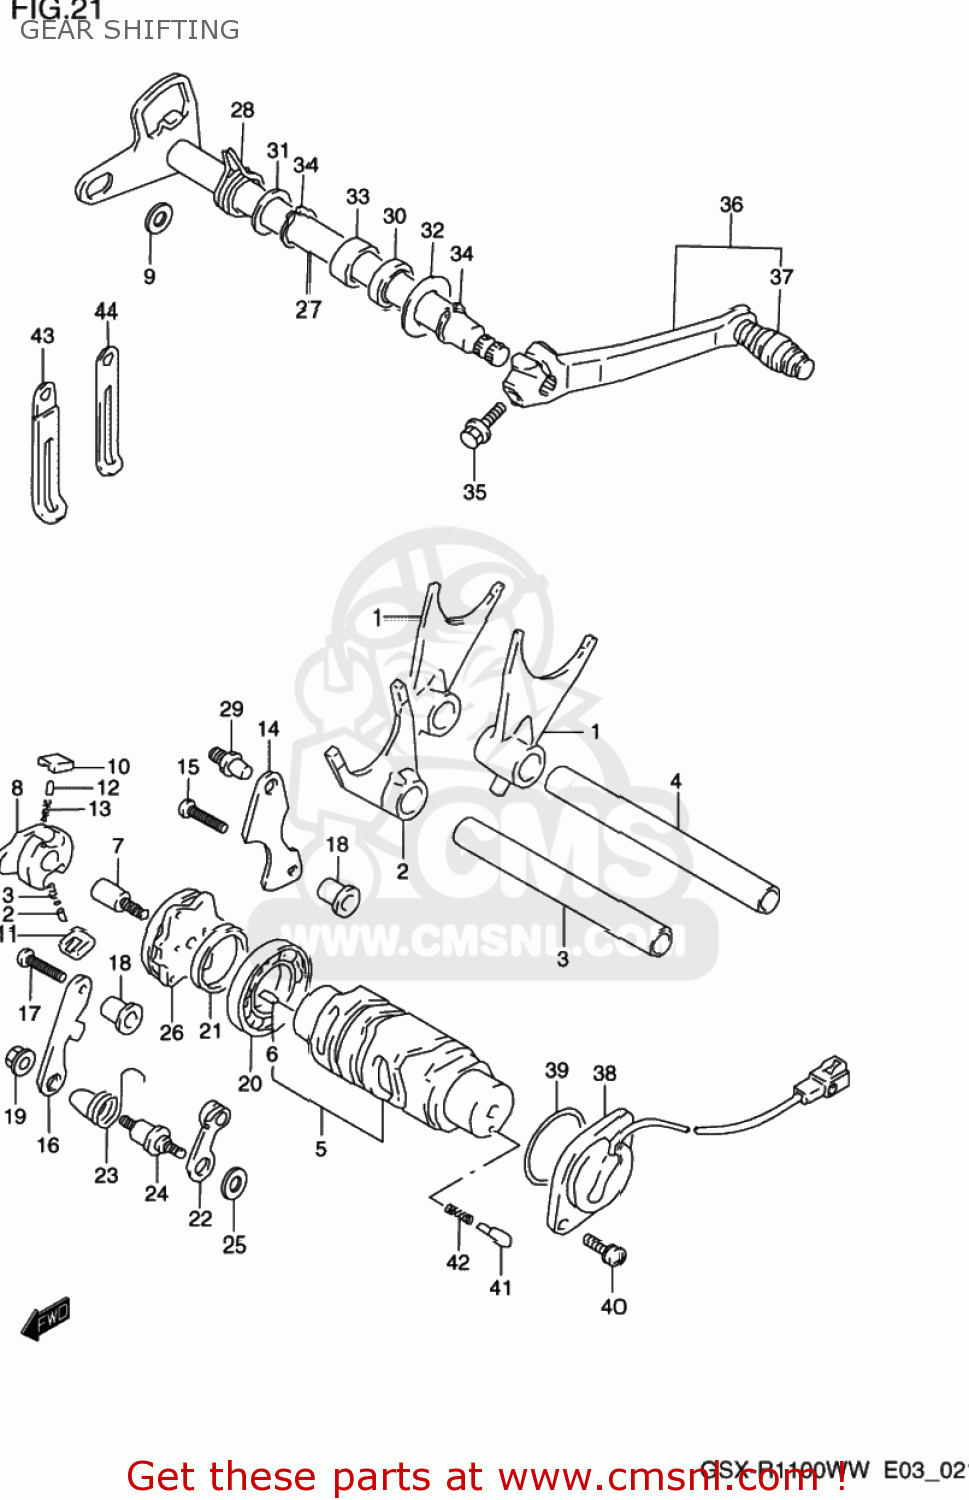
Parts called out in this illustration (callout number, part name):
1	FORK,GEAR SHIFT NO.1
2	FORK,GEAR SHIFT NO.3
3	SHAFT,GEAR SHIFT FORK
4	SHAFT,GEAR SHIFT FORK(L:128)
5	CAM,GEAR SHIFT
6	PIN
7	PIN,SHIFT CAM DRIVEN GEAR
8	SHIFTER,GEAR SHIFT CAM
9	SPACER(7X10X5)
10	PAWL,GEAR SHIFT NO.1
11	PAWL,GEAR SHIFT NO.2
12	PIN(5X8)
13	SPRING
14	LIFTER,GEAR SHIFT PAWL
15	SCREW 6X30
16	GUIDE,GEAR SHIFT CAM
17	SCREW
18	SPACER(6.1X10X16)
19	NUT
20	BEARING
21	WASHER(25X32X3)
22	STOPPER,GEAR SHIFT CAM
23	SPRING,STOPPER ARM
24	SUPPORT,CAM STOPPER ARM
25	WASHER
26	PLATE,GEAR SHIFT CAM
27	SHAFT COMP,GEAR SHIFTING
28	SPRING
29	STOPPER,GEAR SHIFT CAM
30	SEAL,OIL(14X22X6)
31	WASHER,THRUST
32	WASHER
33	BEARING(14X20X12)
34	CIRCLIP
35	BOLT
36	LEVER ASSY,GEAR SHIFT
37	RUBBER,GEAR SHIFT PEDAL
38	BASE ASSY,GEAR SHIFT TERMINAL
39	O RING(D:2.4,ID:36.5)
40	SCREW
41	PIN(5X15.5)
42	SPRING
43	CLAMP
44	CLAMP
